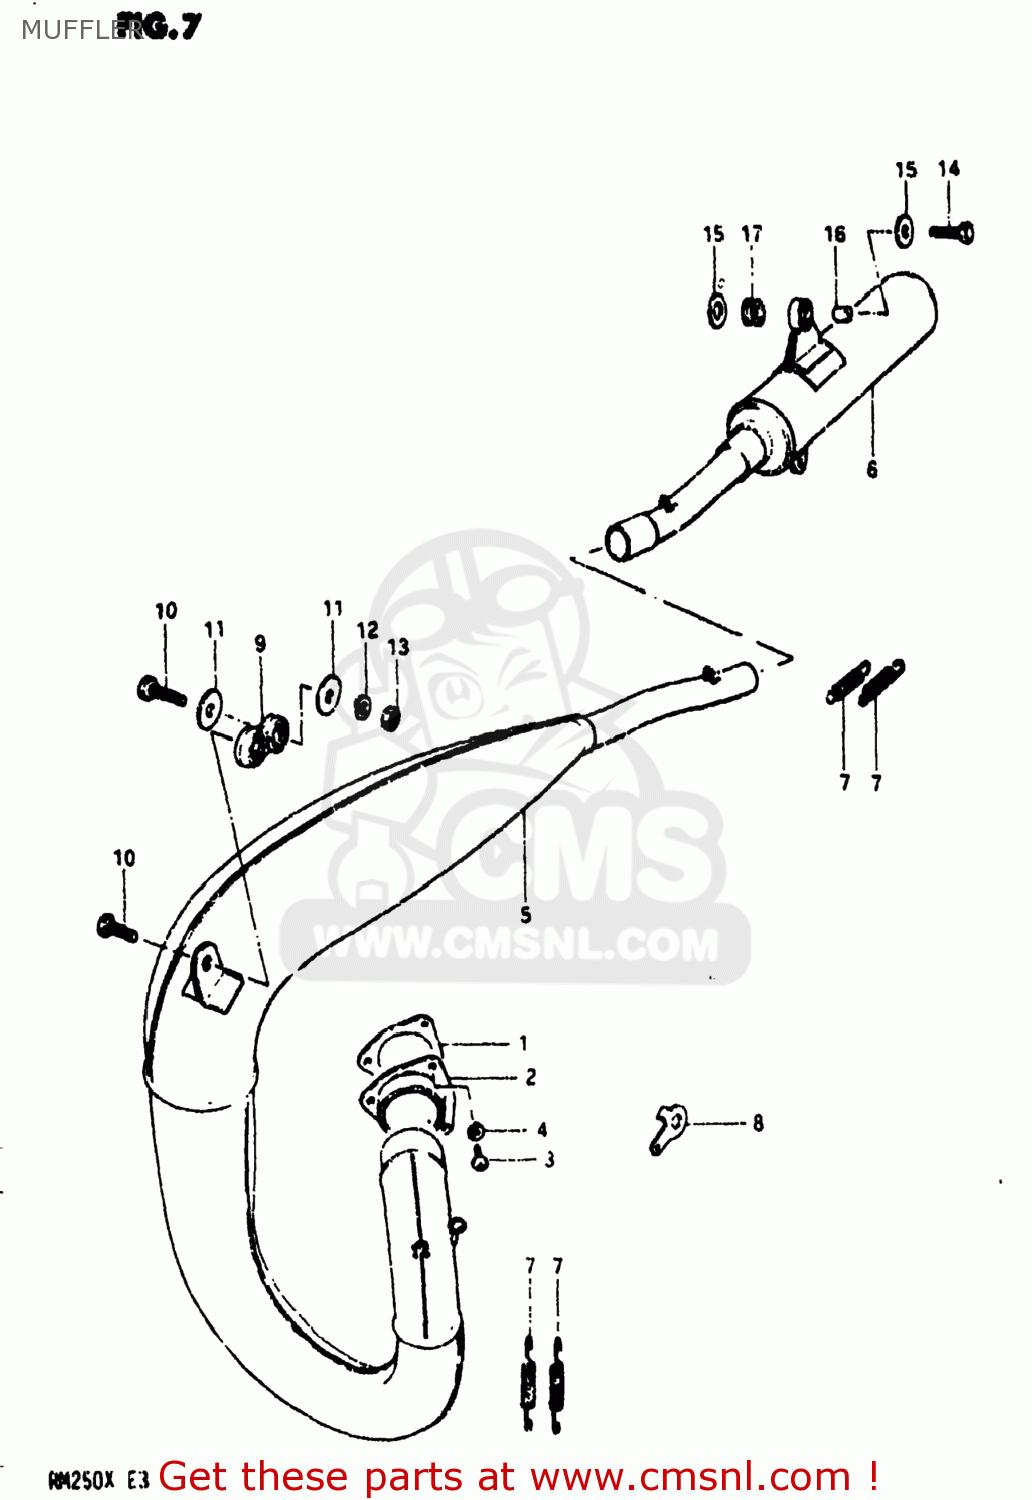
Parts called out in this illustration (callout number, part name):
1	GASKET,EXHAUST PIPE (MCA)
2	FLANGE,EXHAUST PIPE
3	SCREW
4	LOCK WASHER
5	BODY,MUFFLER
6	BODY,MUFFLER
7	SPRING
8	HOOK,MUFFLER FIT SPRING
9	DAMPER,MUFFLER
10	BOLT(8X32)
11	WASHER
12	LOCK WASHER
13	NUT 8MM
14	BOLT(8X32)
15	WASHER (8.5X29X1.6)
16	SPACER (8.6X12X17.5)
17	CUSHION
